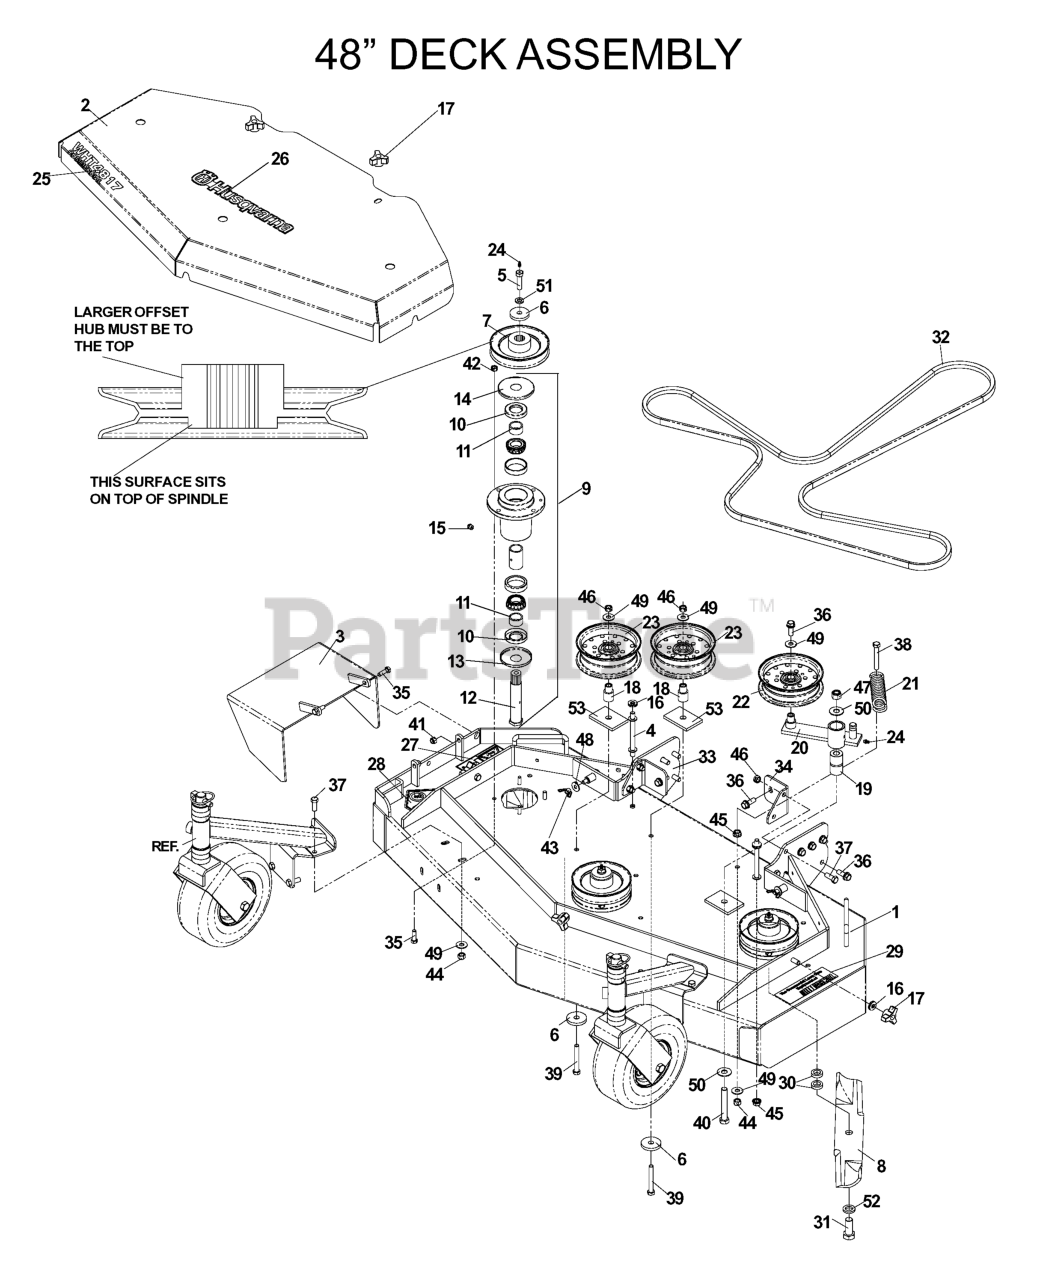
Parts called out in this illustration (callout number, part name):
1	DECK W/DECALS 48"
2	BELT SHIELD, 48" ORANGE
3	DEFLECTOR CHUTE
4	SHIELD SPACER
5	HCS 7/16-20 GD 8 SPEC
6	SPINDLE WASHER
7	PULLEY - 52"
8	BLADE OEM 16 1/4"
9	SPINDLE ASM KIT, WHT/KIKW
10	SHAFT SEAL
12	52/61 SPINDLE - SPLINED SHAFT
13	BOTTOM DUST CAP
14	TOP DUST CAP
15	PLUG-VENTED
16	WASHER, 3/8 SEALING
17	KNOB, THREE PRONG
18	IDLER BUSHING
19	PIVOT BUSHING
22	IDLER PULLEY
23	IDLER PULLEY (TALL)
24	ZERK
25	DECAL, WHT4817
26	DECAL, HUSQ 15" BLUE
27	DECAL, EURO SEVERING
28	DECAL, CPSC
29	DECAL, NASCAR
30	BLADE SPACERS
31	HCS 5/8-18X1-1/2 GR5 TPBLT ZD
33	DECK SLIDE, RT
34	DECK SLIDE, LT
35	HCS 5/16C X 1
36	4CS 3/8C X 1 SERRATED HEAD
37	HCS 3/8-16X1.GRD.5.ZD
38	HCS 3/8C X 2 1/2
39	SCREW 3/8C X 2 3/4 HEX CAP
40	HCS 1/2C X 3 1/4
41	NUT 5/16 NYLOC
42	NUT 5/16C CENTERLOCK
43	WINGNUT, 5/16C NYLOC
44	NUT 3/8-16 NYLOC
45	NUT 3/8C WHIZ
46	NUT 3/8C CENTERBLOCK
47	NUT 1/2-13 HEX NYLOC ZD
48	WASHER 5/16 FLAT
49	WASHER 3/8 FLAT
50	WASHER 1/2 FLAT
51	WASHER 7/16 LOCK
52	LOCKWASHER 5/8
